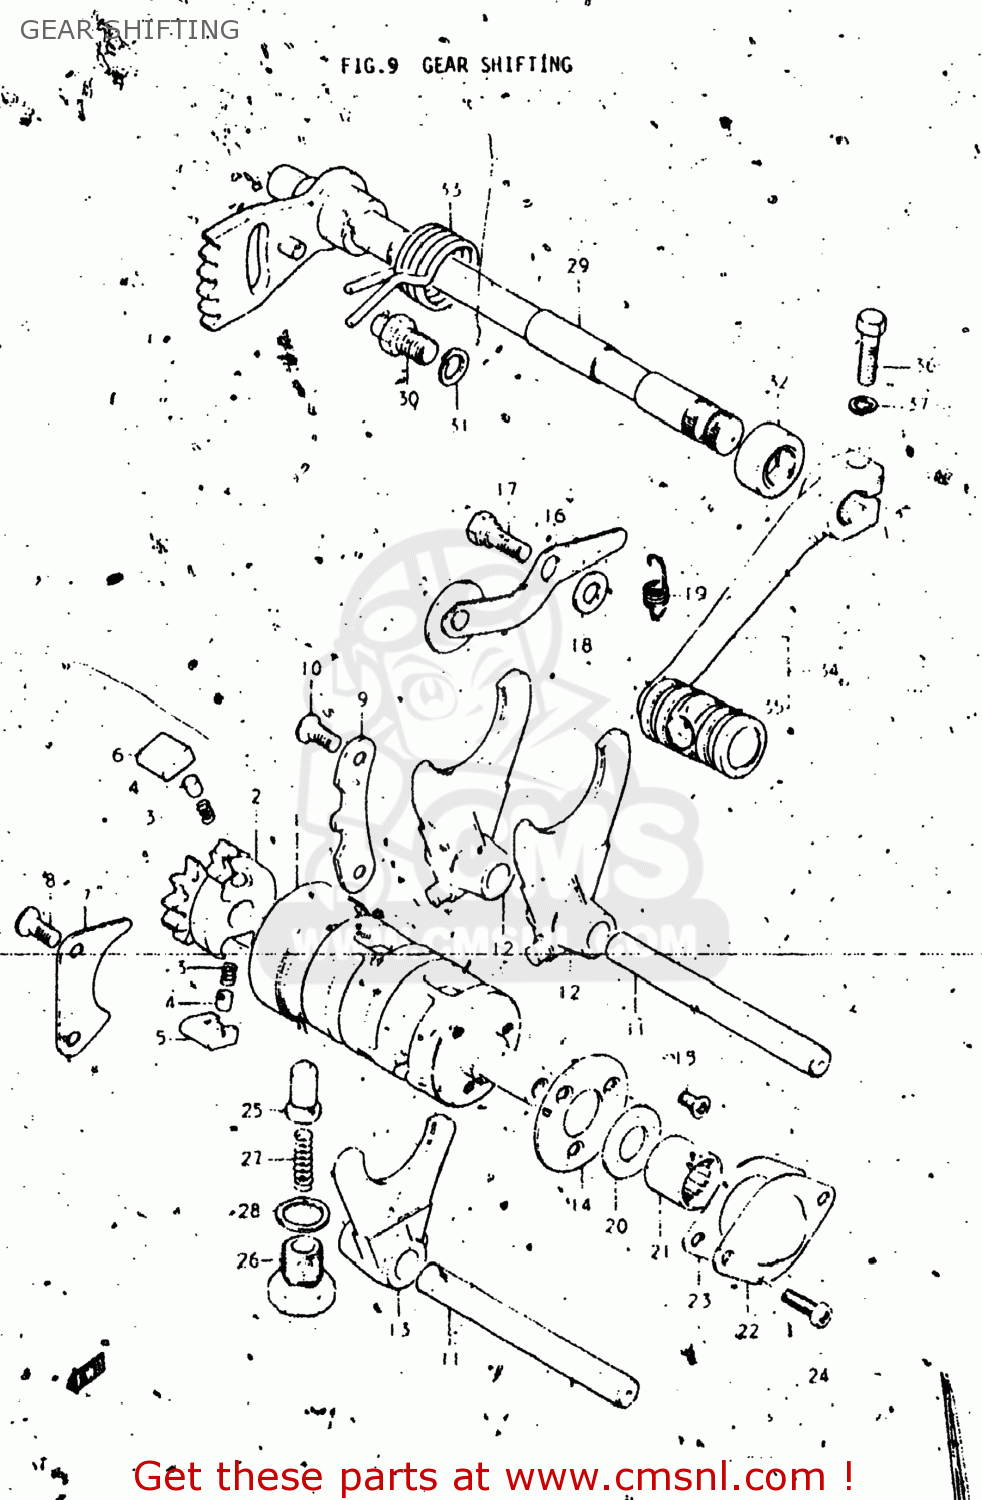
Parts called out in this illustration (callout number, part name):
1	CAM,GEAR SHIFT
2	RETAINER,GEAR SHIFT CAM
3	SPRING
4	PIN(5X8)
5	PAWL,GEAR SHIFT NO.1
6	PAWL,GEAR SHIFT NO.2
7	LIFTER,GEAR SHIFT PAWL
8	SCREW
9	GUIDE,GEAR SHIFTING CABLE
10	SCREW
11	SHAFT,GEAR SHIFT FORK
12	FORK,GEAR SHIFT NO.1
13	FORK,GEAR SHIFT NO.3
14	PLATE,GEAR SHIFT CAM
15	SCREW
16	STOPPER,GEAR SHIFTING
17	BOLT(6X16.1)
18	WASHER
19	SPRING
20	WASHER
21	ROLLER BEARING (12X18X1
22	CAP,CAM PIVOT
23	GASKET (MCA)
24	SCREW
25	STOPPER,GEAR SHIFTING
26	HOLDER,GEAR SHIFT CAM STOP SPR
27	SPRING
28	GASKET(14X19.2X2) (NAS)
29	SHAFT,GEAR SHIFT
30	STOPPER,GEAR SHIFT CAM
31	LOCK WASHER
32	OIL SEAL
33	SPRING
34	LEVER ASSEMBLY,GEAR SHIFTING
35	RUBBER,GEAR SHIFT PEDAL
36	BOLT
37	LOCK WASHER
